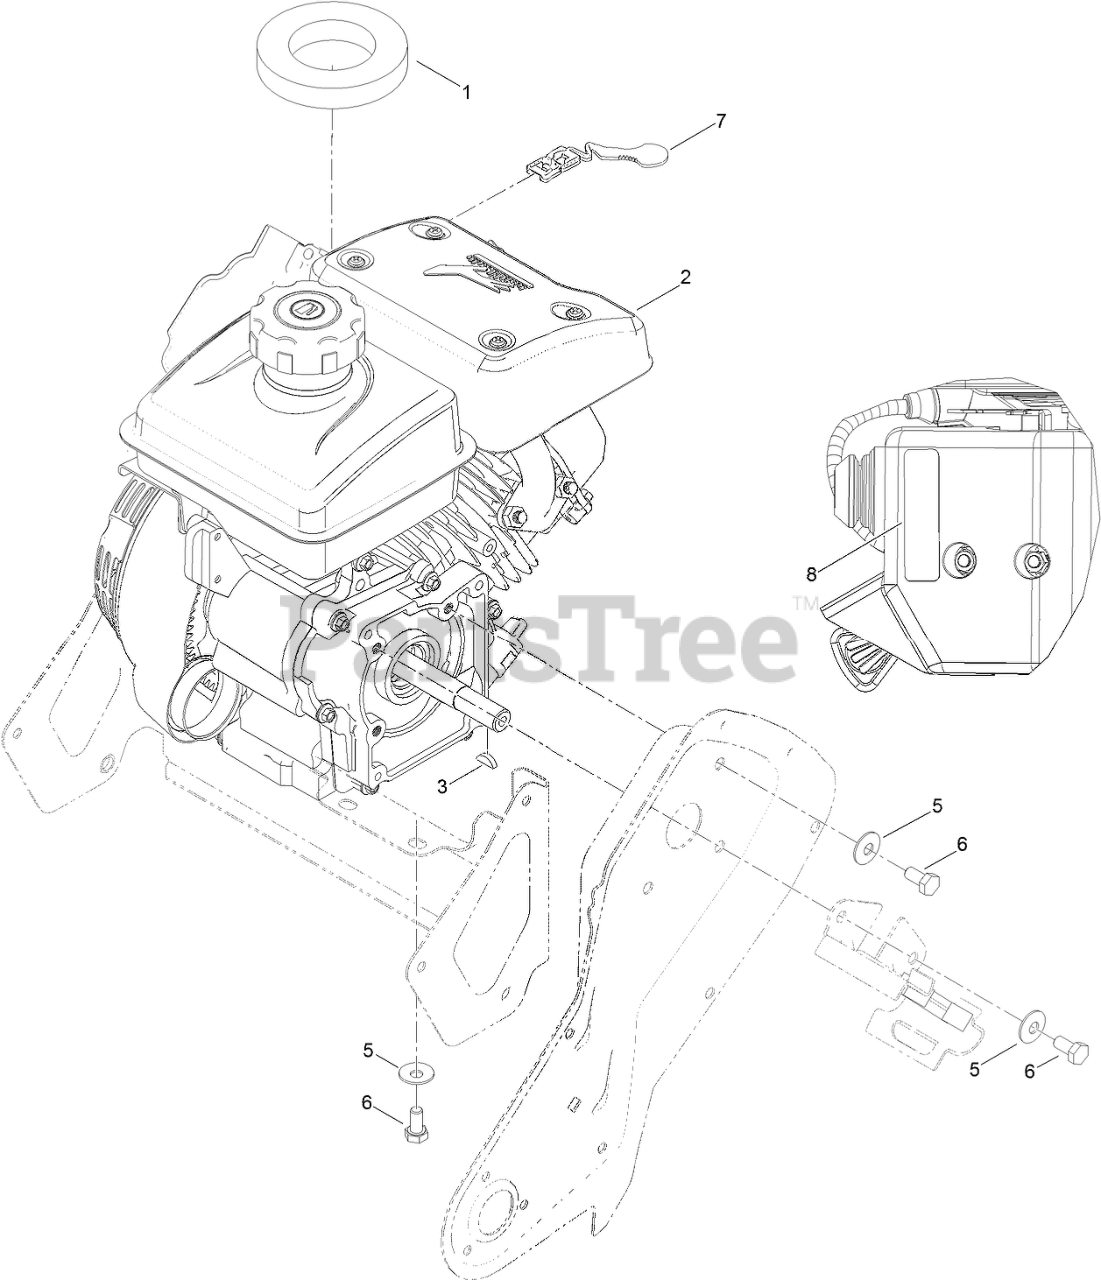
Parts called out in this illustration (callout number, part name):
1	SEAL-TANK
2	ENGINE-156FS
3	KEY-WOODRUFF
5	WASHER-BELLEVILLE
6	SCREW-HH
7	LEVER-CHOKE
8	DECAL-CONTROLS, ENGINE
